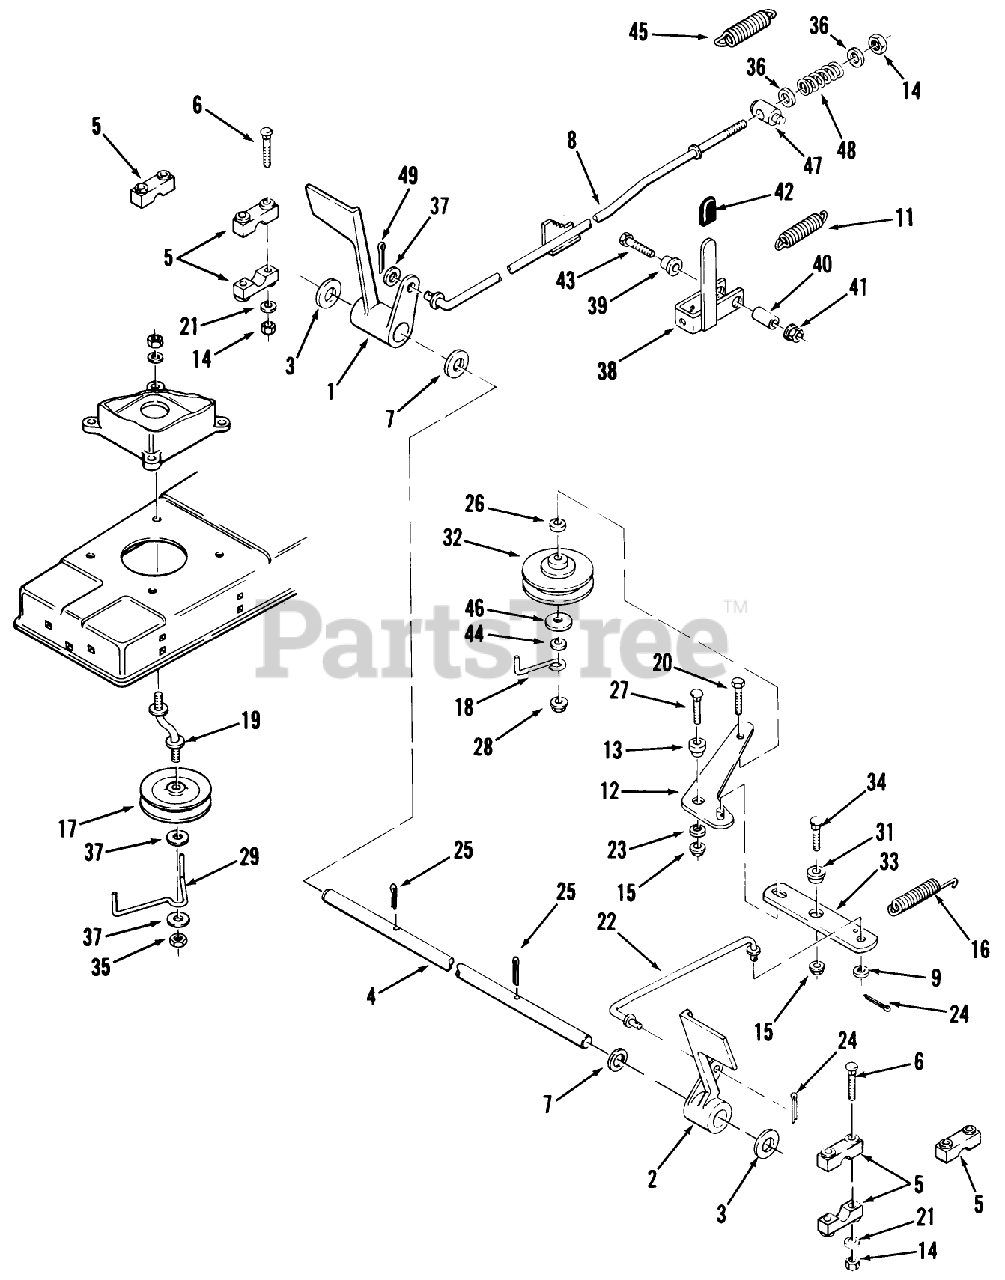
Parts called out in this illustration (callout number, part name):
1	PEDAL-BRAKE *R
3	WASHER-SPECIAL
9	WASHER 5/16 SAE
11	SPRING-EXTENSION
13	SPACER-IDLER ARM
16	SPRING
17	PULLEY-IDLER STATION
21	WASHER 5/16 SAE
22	ROD-CLUTCH *R
32	IDLER PULLEY
38	PAWL-HANDLE ASSY
39	SPACER
40	SPACER
42	GRIP
45	SPRING-EXTENSION
46	WASHER
47	TRUNNION-LIFT
